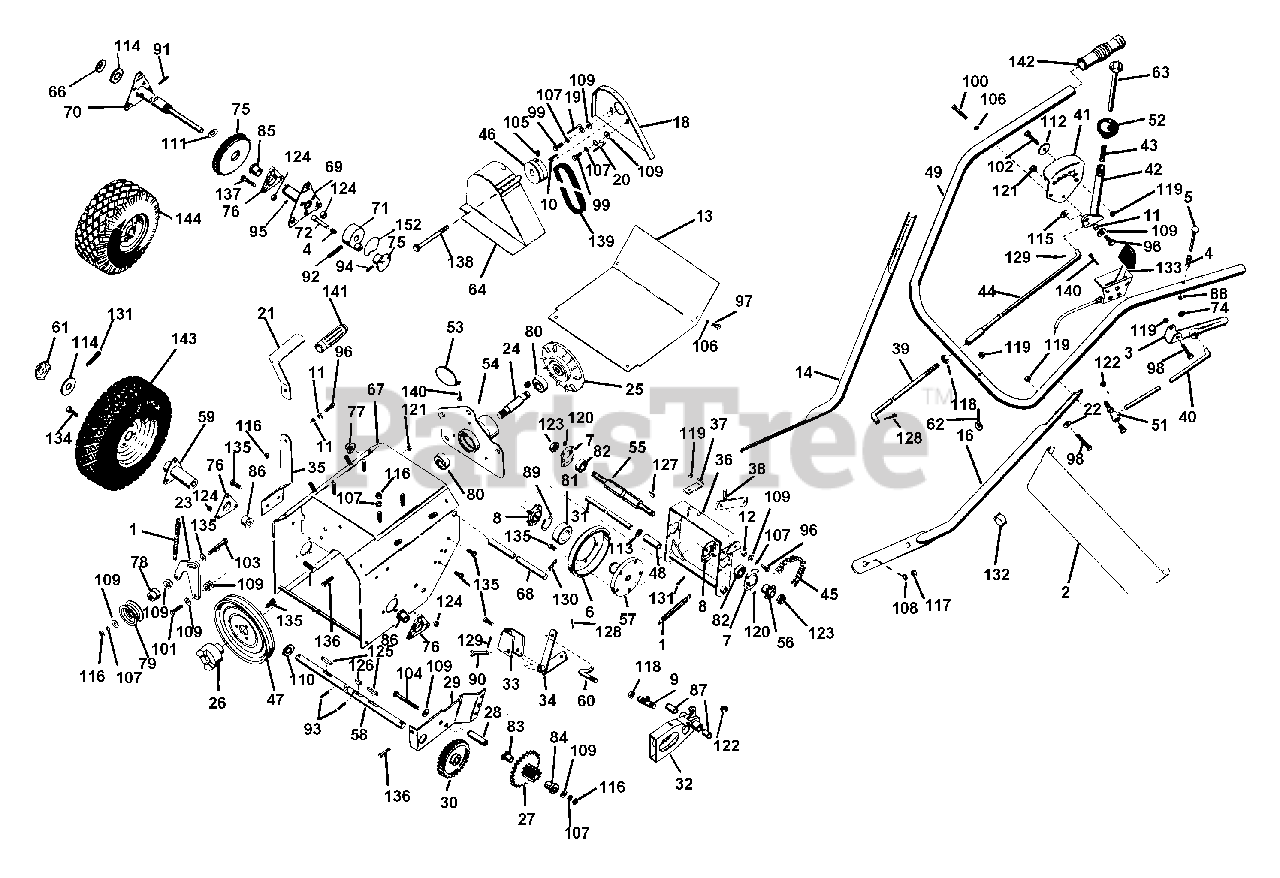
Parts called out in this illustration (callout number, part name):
1	SPRING
2	HANDLE BAR PANEL
3	CLUTCH HANDLE
4	SG-COMP ??X.44X?? WLD 10
5	CLUTCH LOCK PIN
6	FRICTION DISC
7	BEARING FLANGE
8	BEARING FLANGE
9	BALL JOINT
11	SPACER BUSHING .5 X .32 X .21
12	SPACER BUSHING .5 X .32 X .163
13	BOTTOM COV
14	R H LOWER HANDLE BAR
16	L H LOWER HANDLE BAR
18	INNER BELT GUARD
19	R H BELT FINGER
20	L H BELT FINGER
21	CLTCH LEVER
22	HANDLE BAR WASHER
23	IDLER ARM
24	SPINDLE
25	DRIVE PLATE
26	JAW COUPLING
27	PINION & SPROCKET
28	PINION STUB SHAFT
29	SUPPORT BRACKET
30	SPUR GEAR, FELLOWS 35T .750 ID
31	BRACKET PIN
32	SLIDING FORK
33	LEVER BRACKET
34	TRANSFER LEVER
35	CLTCH BRCKT
36	DISC BRCKT
37	NEUTRAL CATCH
38	THROWOUT LEVER
39	LOWER SHIFT ROD
40	CLTCH ROD
41	SHIFT QUADRANT
42	SHIFT HANDLE
43	SPRING
44	SHIFT ROD
45	ROLLER CHAIN
46	ENGINE SHEAVE
49	UPPER HANDLE BAR
51	BALL JOINT
52	SHIFT BALL
54	BEARING HOUSING
55	HEX SHAFT
56	9 TOOTH SPROCKET
57	FRICTION DISC HUB
58	AXLE SHAFT
59	WHEEL HUB
60	CONNECTING LINK
61	HUB CAP
62	ROD HANGER EYEBOLT
63	SHIFT RELEASE HANDLE
64	OUTER BELT GUARD
65	CARB COVER
66	PUSHNUT
67	TRACTOR FRAME
68	FORK SHFT
69	L H AXLE
70	R H AXLE SHAFT
71	LOCKOUT HUB
72	PIN
73	KNOB
74	RATCHET PLATE
75	Differential Assembly(10M6D,10M7D)
76	SUPPORT, BEARING
77	CAP, .50 ROD YWZC
78	SPCR, BRG .315X.50X.688X.281
79	IDLER
80	BRG-BALL .750X1.750X.50
81	BRG-BALL 1.25X2.18X.63
82	BRG-BALL .500X1.38X.437
83	BSHG-FLG .625X.750X.500X.875BR
84	BSHG-SLV .562X.625X.625 BRZ
85	BSHG-FLG.875X1X.625X1.250 BR
86	BSHG-FLG .750X1.000X.625X1.250
87	BSHG-SLV .500X.625X.500 BR
88	RG-RTNG-EXT .250X.031
89	RG-RTNG-EXT 1.250X.050
90	CLEVIS PIN
91	PIN-ROLL .188X1.25
92	PIN-ROLL .250X1.25
93	PIN-ROLL .250X1.25
94	PIN-ROLL .188X1.25
95	HYDRAULIC DRIVE FITTING
96	BLT-HEX .31-18X.63 PL GR 2
97	BLT-HEX .31-18X.63 PL GR 2
98	BLT-HEX .38-16X1.25 PL GR 2
99	BLT-HEX .38-16X1.25 PL GR 2
100	BLT-HEX .38-16X1.25 PL GR 2
101	BLT-HEX .38-16X1.50 PL GR2
102	BLT-HEX .44-14X1.25 PL GR2
103	BLT-HEX .44-14X1.25 PL GR2
104	BLT-HEX .44-14X1.25 PL GR2
105	SCR-SET .38-16X.50 SKHCUP OH
106	WSHR-LK .250X.077 HVY PL
107	WSHR-LK .312X.097 PL HVY
108	WSHR-LK .375X.115 HVY PL
109	WSHR-FL-STL .38X.875X.083 PL
110	WSHR-FL-STL .531X1.062X.095 PL
111	WSHR-FL-STL .531X1.062X.095 PL
112	WSHR-FL-STL .531X1.062X.095 PL
113	BRG-NEEDLE .625X.812X.50
114	WSHR-FL-STL .755X2.000X.125
115	WSHR-FL-STL.406X.812X.065PL
116	NUT-JAM .375-16 PL
117	NUT-JAM .375-16 PL
118	NUT-HEX .312-24 PL
119	NUT-LK-CTR .250-20 PL
120	NUT-LK TOP 10-24 PL
121	NUT-LK .312-18 GR A PL
122	NUT-LK-CTR .312-24 PL
123	NUT-LK-CTR .50-20 PL
124	NUT-LK-FLG .250-20 PL
125	KEY-WDRF .188X.875X.375 SAE11
126	KEY-WDRF .188X.875X.375 SAE11
127	KEY-WDRF .188X.875X.375 SAE11
128	PIN-COTR .09X.75 PL
129	PIN-COTR .12X1.0 PL
130	PIN-COTR .09X.75 PL
131	PIN-COTR .09X.75 PL
132	THROTTLE CONTROL
133	THROTTLE CONTROL
134	BRG-CUP 2.441X.562
135	BLT-SERHFWH .31-18X.50 PL
136	BLT-SCRHFWH .38-16X.50 PL
137	SCR-SLTR-SERNK .25-20X.62 PL
138	BLT-HFWH .31-24X3.62 PL
139	V-BELT, SAE 380-RAW EDGE
140	SCR-TAP 10-12X.50 CRPH PL A
142	GRIP
143	T/WHL ASSY
143	TIRE 4.10/3.50X6 2PLY
143	TUBE
143	WHL 6 IN O.D.
143	WHL
144	Tire and Wheel Assembly(10M7D)
144	TIRE 12.5/4.50-6
144	TUBE
144	WHL 6 IN O.D.
145	DISCHARGE CAUTION LABEL
146	DISCHARGE CAUTION LABEL
147	DISCHARGE CAUTION LABEL
148	DISCHARGE CAUTION LABEL
149	MOWER IN-OUT LABEL
150	MOWER IN-OUT LABEL
151	MOWER IN-OUT LABEL
152	MOWER IN-OUT LABEL
